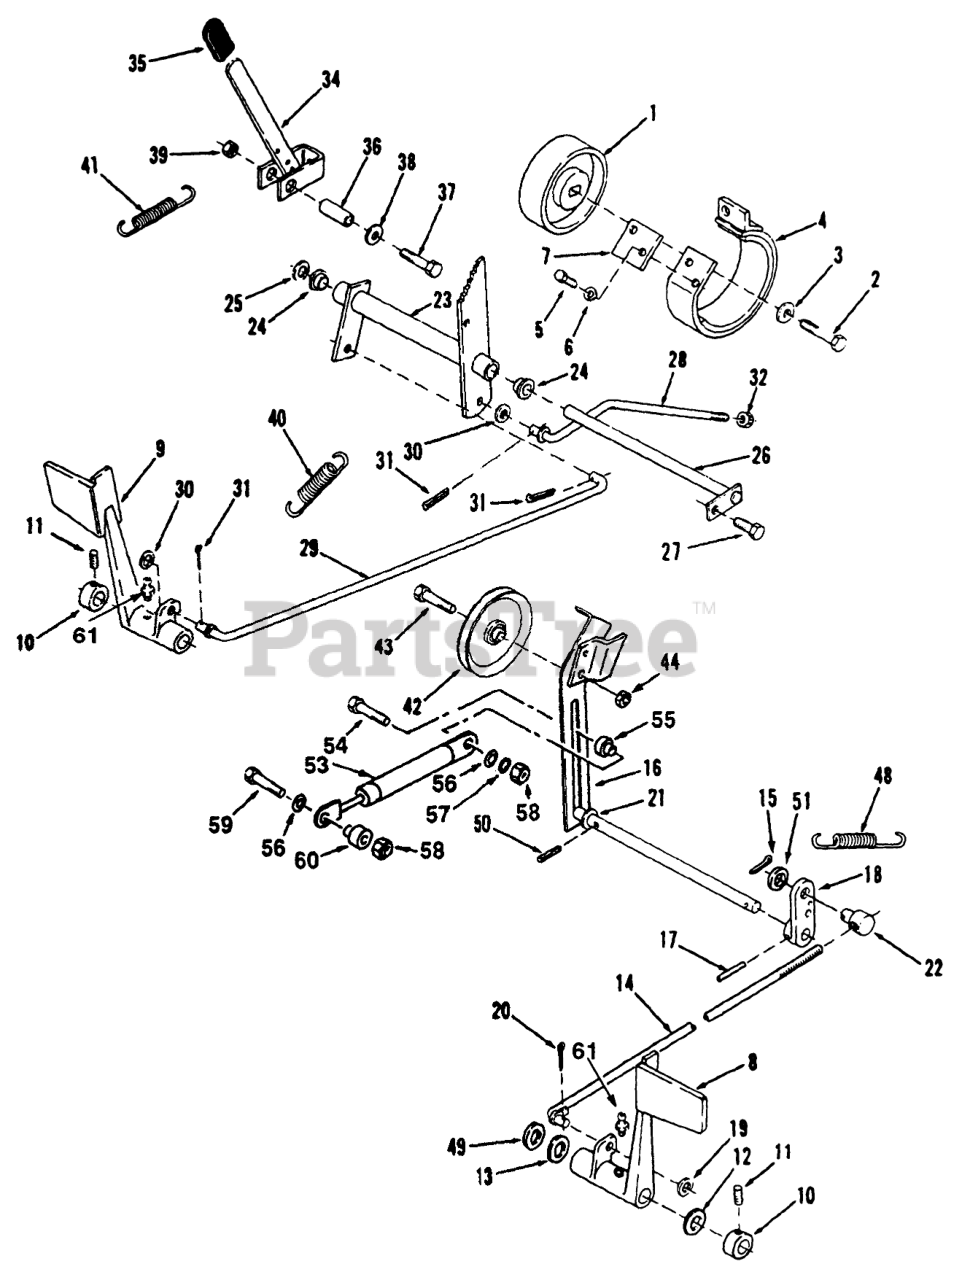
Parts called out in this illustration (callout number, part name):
1	DRUM-BRAKE
2	SCREW-HEX HD CAP
3	WASHER
4	BRAKE BAND ASM
5	SCREW-HH
6	WASHER-LOCK
7	Plate-Stop
8	PEDAL-CLUTCH R
9	Pedal-Brake
10	Collar
11	SCREW-HSH
12	WASHER-BOWED
13	WASHER
14	ROD AND GUIDE ASM
15	PIN-COTTER
16	Arm-Clutch Idler
17	PIN-SPIROL
18	Arm-Clutch Rod
19	WASHER-NYLON
20	PIN-COTTER
21	SHIM-WASHER
22	TRUNNION
23	Bellcrank Assy
24	BUSHING-FLANGED
25	WASHER-FLAT
26	ROD ASM
27	SCREW
28	ROD-REAR BRAKE
30	WASHER-NYLON
31	PIN-COTTER
32	NUT-LOCK, NI
34	ASSY-BRAKE LEVER WAB
35	GRIP
36	SPACER
37	SCREW-HH
38	WASHER-FLAT
39	LOCKNUT-FLANGE
40	SPRING-BRAKE
41	SPRING-EXTENSION
42	PULLEY-IDLER
43	BOLT-SPECIAL HEX
44	NUT-LOCK, NI
48	SPRING-CLUTCH
49	Washer
50	PIN-SPIROL
51	WASHER-FLAT
53	ASS'Y-GAS SPRING
54	SCREW-HH
55	SPACER-SHOULDER-.200
56	WASHER-FLAT
57	WASHER-LOCK
58	NUT-LOCK, NI
59	SCREW-HH
60	SPACER-SHOULDER-.400
61	FITTING-GREASE
